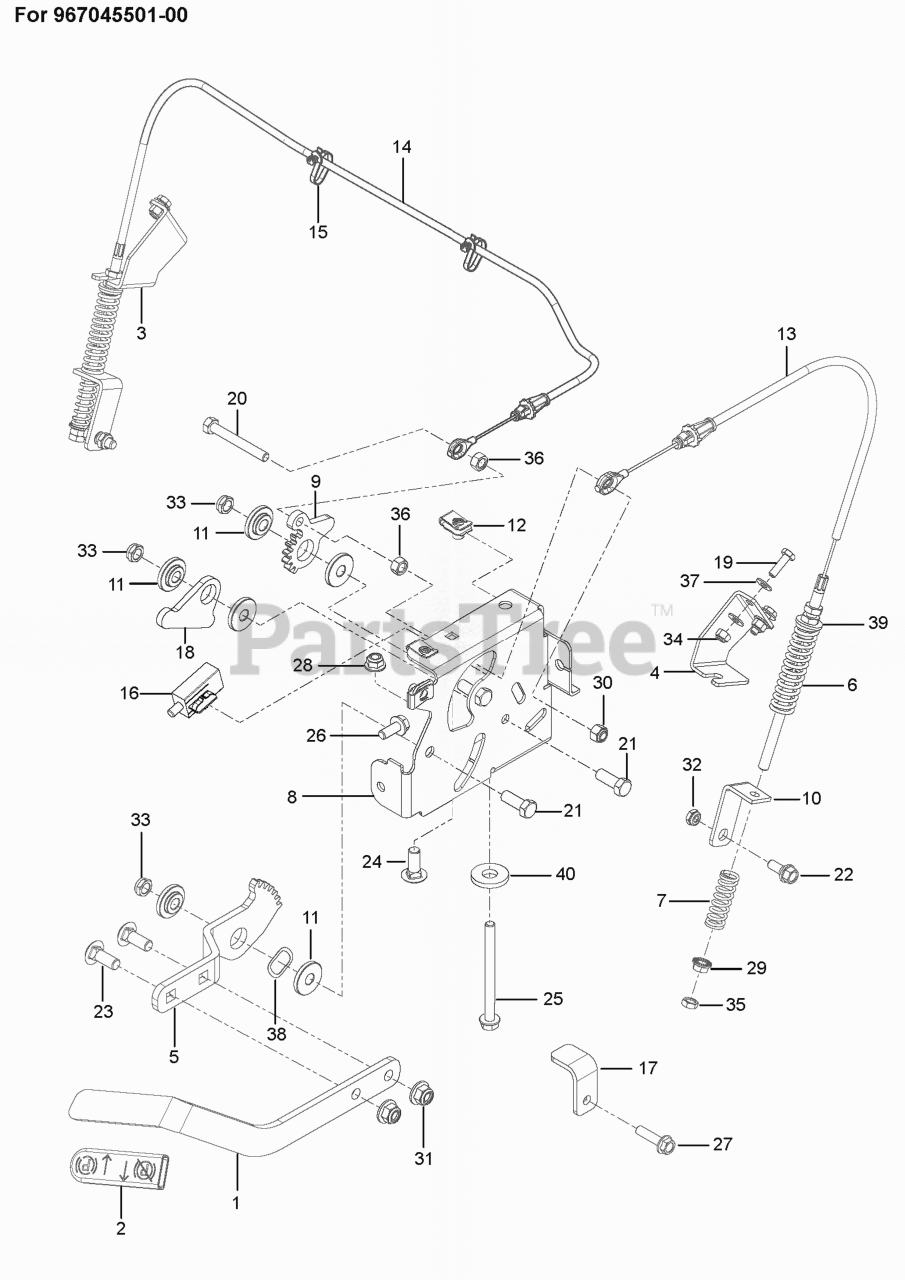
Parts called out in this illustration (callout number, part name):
1	ARM BRAKE BLACK MS-431
2	GRIP, PARK BRAKE
3	BRACKET BRAKE, RT BLACK MS-431
4	BRACKET BRAKE, LT BLACK MS-431
5	GEAR.INPUT.PARKING.BRAKE.MZ
6	SPRING, RETURN
7	SPRING, ENGAGEMENT
8	MOUNT.PNT.BRAKE.MZ.EDIP
9	GEAR OUTPUT;PARKING BRAKE;STAN
10	NUT 5/16C HEX
11	BRACKET.PNT.LIMIT.ARM.BRK.EDIP
12	U-CLIP 5/16-18 NUT RETAINER
13	CABLE.ASSY.BRAKE.CABLE.SHORT
14	CABLE.ASSY.BRAKE.CABLE.LONG
15	CABLE.ASSY.BRAKE.CABLE.SHORT
16	CABLE.ASSY.BRAKE.CABLE.LONG
17	BRACKET.PNT.LIMIT.ARM.BRK.EDIP
18	ACTUATOR.PARK.BRAKE.MZ.SRV.431
19	HCS 1/4-20X7/8 GR5
20	HCS 5/16-18 X 2 1/2 TPBLT
21	HHFS 5/16-18 X 1.25 TPBLT GD 5
22	BOLT, SHOULDER
23	RHSNB 3/8C X 1
24	BOLT 5/16C X 3/4" CARRIAGE
25	HHFS 5/16-18 X 3 3/4
26	HHFS 5/16-18 X 3/4
27	HHFS 5/16-18 X 1.25 TPBLT GD 5
28	5/16-18 NYLOC FLANGE NUT
29	NUT 5/16C WHIZ
30	NUT 5/16 NYLOC
31	NUT 3/8-16 HEX FLG NYLOC ZD
32	5/16-18 THIN PROF NY
33	NUT HEX 3/8-16 NYLON, THIN
34	NUT.1/4-20.HEX.NYLOC.ZD
35	NUT 5/16-18 HEX JAM ZD
36	NUT 5/16C HEX
37	WASHER 1/4 SAE
38	WASHER.9/16 X 1 3/8 X 12 GA.
39	WASHER 3/8 SAE FLAT
40	WASHER.9/16 X 1 3/8 X 12 GA.
